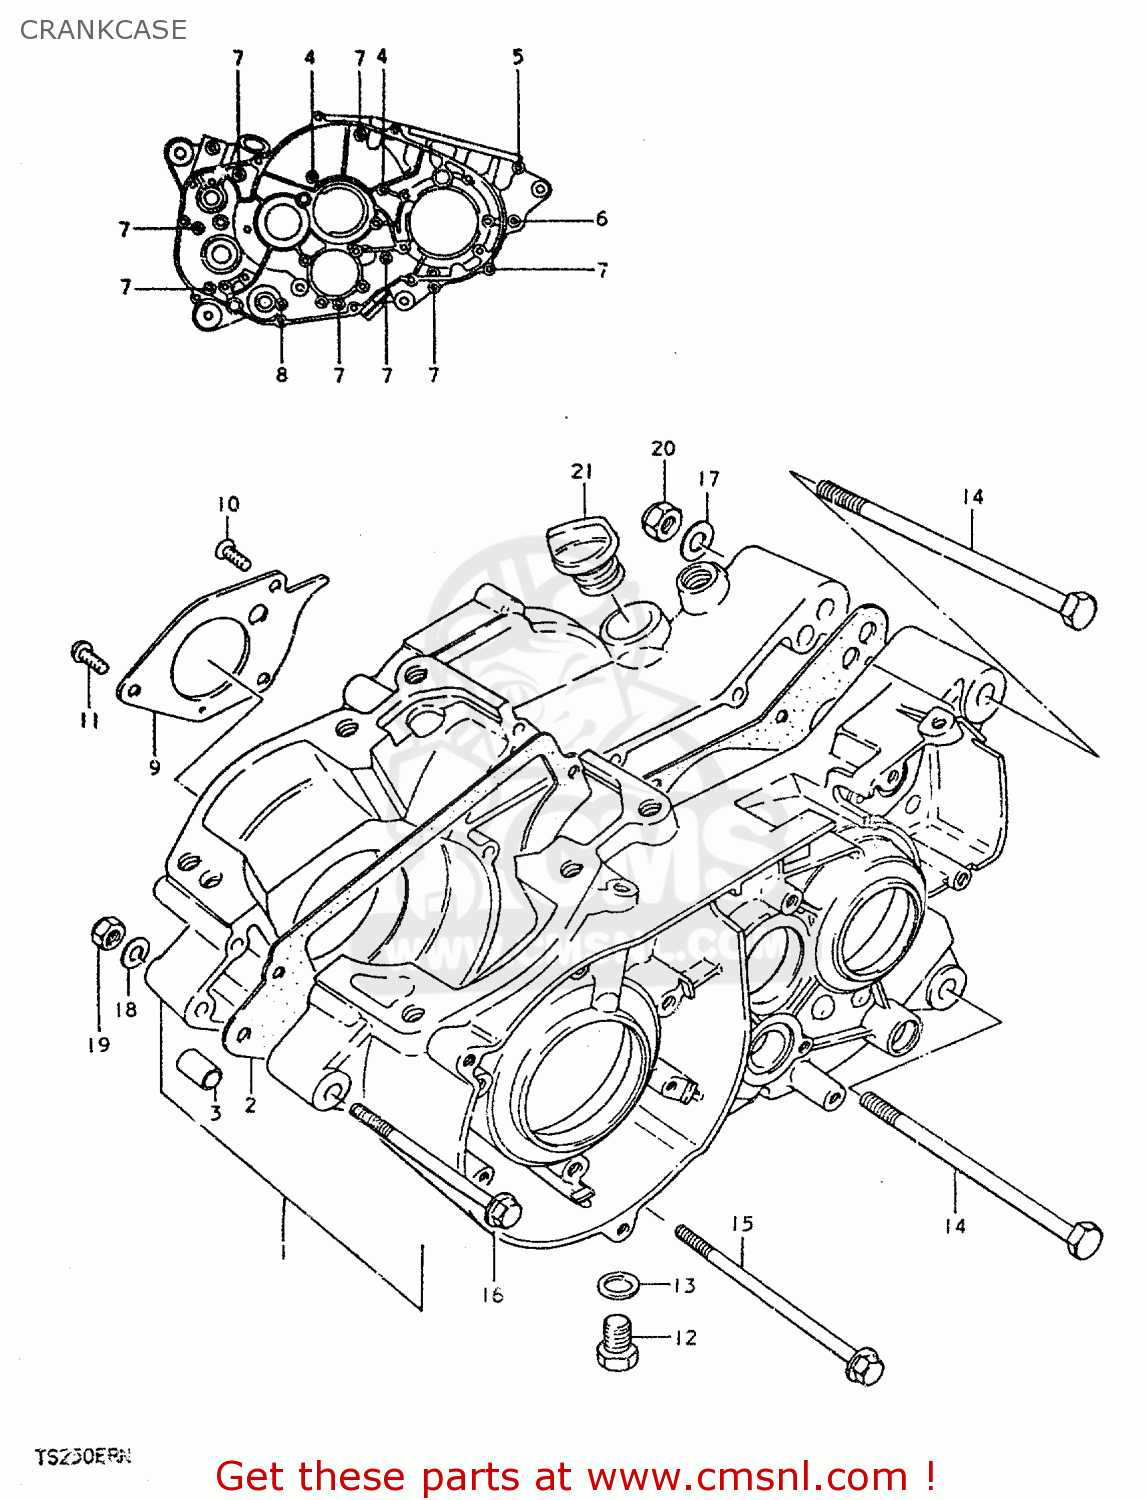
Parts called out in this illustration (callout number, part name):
1	CRANKCASE SET
2	GASKET,CRANKCASE (MCA)
3	PIN
4	SCREW
5	SCREW 6X65
6	SCREW
7	SCREW (6X45)
8	SCREW (6X35)
9	PLATE,OIL RESERVOIR
10	SCREW
11	SCREW
12	PLUG
13	GASKET(14X19.2X2) (NAS)
14	BOLT
15	BOLT
16	BOLT
17	WASHER
18	WASHER
19	NUT
20	NUT
21	PLUG
